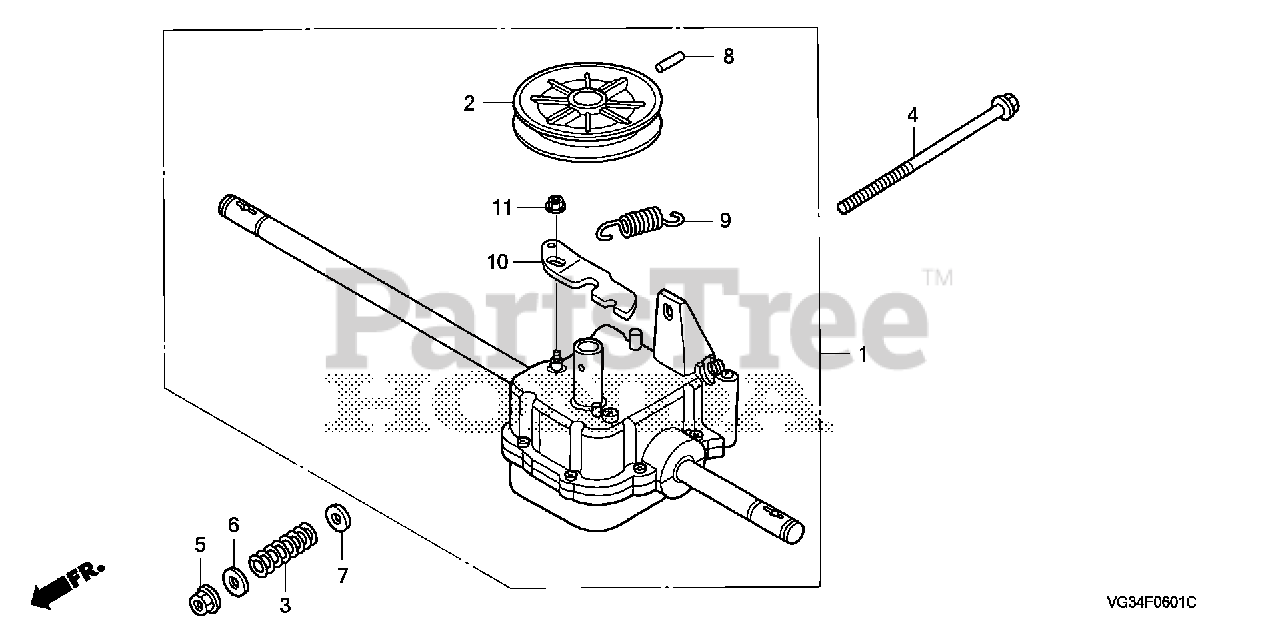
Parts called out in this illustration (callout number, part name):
1	TRANSMISSION ASSY.
2	PULLEY, DRIVEN
3	SPRING, BELT TENSIONER
4	BOLT, FLANGE (6X135)
5	NUT, NYLON LOCK (6MM)
6	WASHER, PLAIN (8MM)
7	WASHER, PLAIN (6MM)
8	PIN, SPRING (5X36)
9	SPRING, CLUTCH ARM RETURN
10	ARM, CLUTCH
11	NUT, LOCK (5MM)
